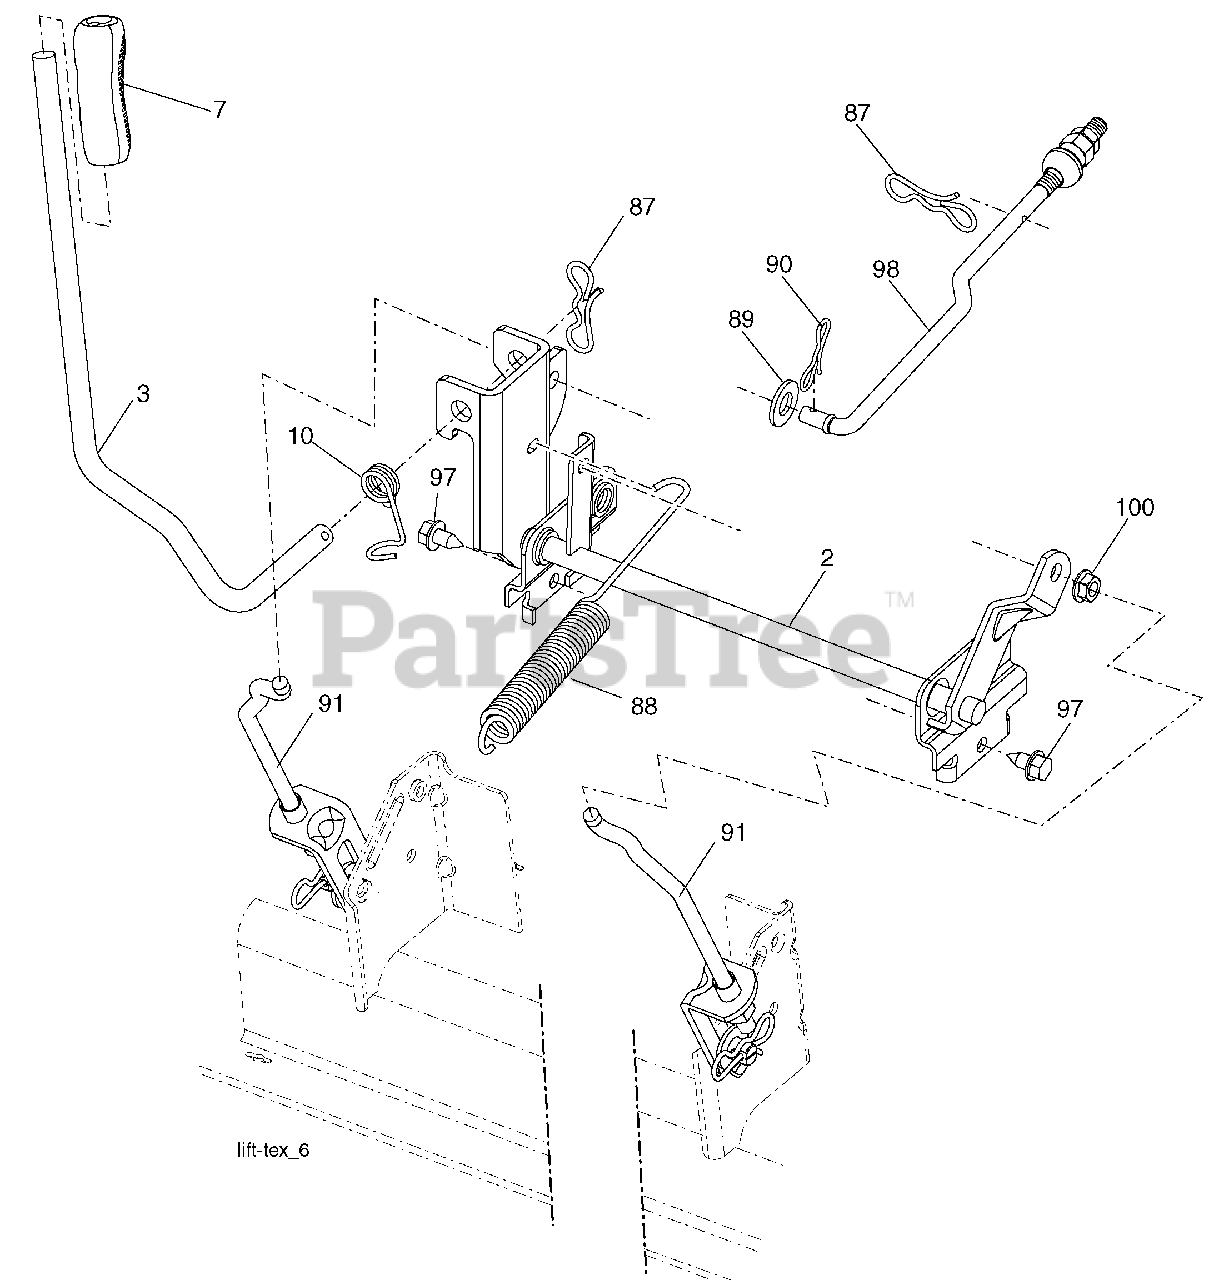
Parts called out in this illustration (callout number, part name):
2	Shaft Asm., Lift
3	Lever Asm., Lift Rh
7	Grip, Lever
10	Spring Torsion
87	Pin Cotter 7/16 Bow Tie Lock
88	Spring Lift Assist
89	Washer Clear Zinc
90	Pin Cotter 5/16 Bow Tie Lock
91	Link Asm. Lift Rear
97	Screw 3/8-16 x .75 R.Z
98	Link Lift Susp. Front Mower
100	Nut Centerlock 3/8-16 unc
